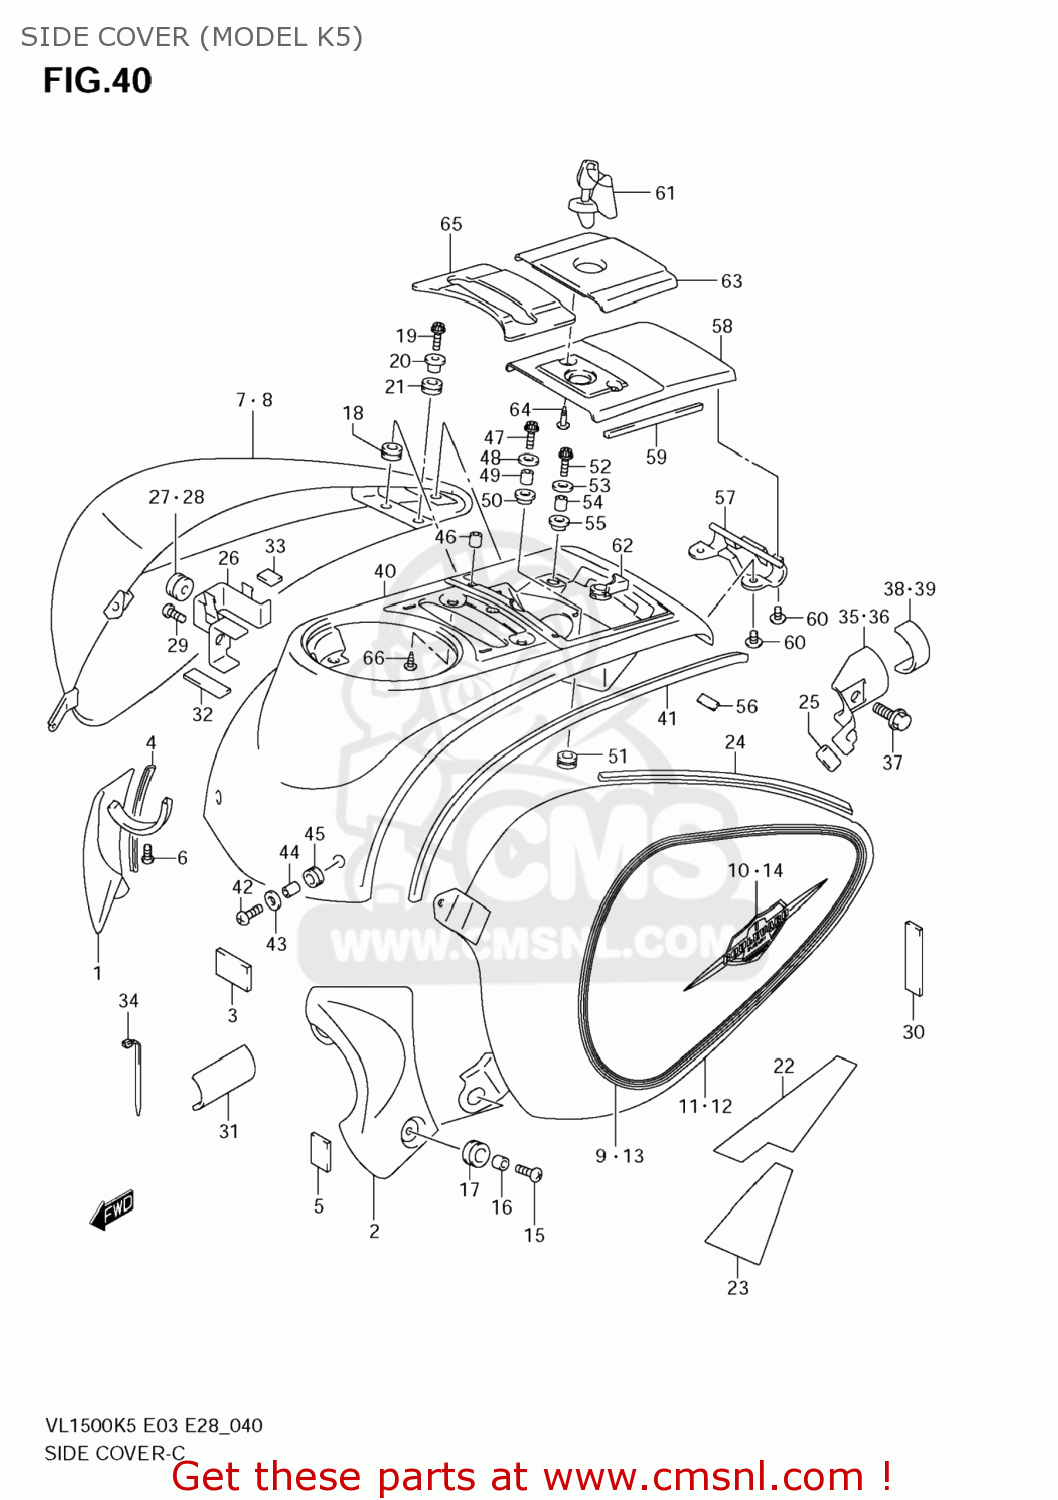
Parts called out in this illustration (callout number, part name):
1	COVER,FRAME HEAD,R
2	COVER,FRAME HEAD,L
3	CUSHION,METER COVER RE
4	MOLDING,FRAME HEAD COVER
5	PROTECTOR,FRAME COVER
6	SCREW(6X20)
7	COVER ASSY,SIDE UPR,R
8	COVER ASSY,SIDE UPR,R
9	TAPE,SIDE COVER UPR,R
10	EMBLEM,SIDE CO
11	COVER ASSY,SIDE UPR,L
12	COVER ASSY,SIDE UPR,L
13	TAPE,SIDE COVER UPR,L
14	EMBLEM,SIDE CO
15	SCREW(6X16)
16	SPACER(6.5X9X7.2)
17	CUSHION
18	CUSHION,SIDE UP METER & FRAME
19	BOLT
20	WASHER,SIDE UPR COVER
21	CUSHION,SIDE UPR COVER
22	SHIELD,SIDE UPR COVER,R
23	SHIELD,SIDE UPR COVER,L
24	MOLDING,SIDE UPR COVER UNDER
25	CUSHION,BRACKET
26	BRACKET,SIDE UPR COVER
27	CUSHION
28	CUSHION
29	BOLT
30	TAPE,HEAT SHIELD
31	CUSHION,SIDE COVER FR
32	PROTECTOR,STARTING MOTOR LEAD
33	PROTECTOR,CTR
34	CLAMP(L:165)
35	BRACKET,SIDE UPR COVER,R
36	BRACKET,SIDE UPR COVER,L
37	BOLT
38	CUSHION,BRACKET NO.1
39	CUSHION,BRACKET NO.2
40	COVER,METER & FUEL INLET
41	MOLDING,METER COVER
42	SCREW(6X16)
43	WASHER(6.5X18X1.5)
44	SPACER(6.5X9X5.7)
45	CUSHION
46	CUSHION
47	BOLT,OIL PAN
48	WASHER(6.5X18X1.6)
49	SPACER(6.5X9X11)
50	CUSHION,METER COVER
51	CUSHION,SIDE UP METER & FRAME
52	BOLT MAGNETO S
53	WASHER(6.5X18X1.6)
54	SPACER(6.5X9X5.7)
55	CUSHION
56	CUSHION,METER COVER RE
57	HINGE COMP,FUEL LID
58	LID,FUEL INLET
59	CUSHION,FUEL LID
60	SCREW 6X12
61	LOCK SET,COVER
62	CUSHION,RR,L
63	COVER,FUEL LID
64	SCREW
65	COVER,METER SWITCH
66	SCREW
